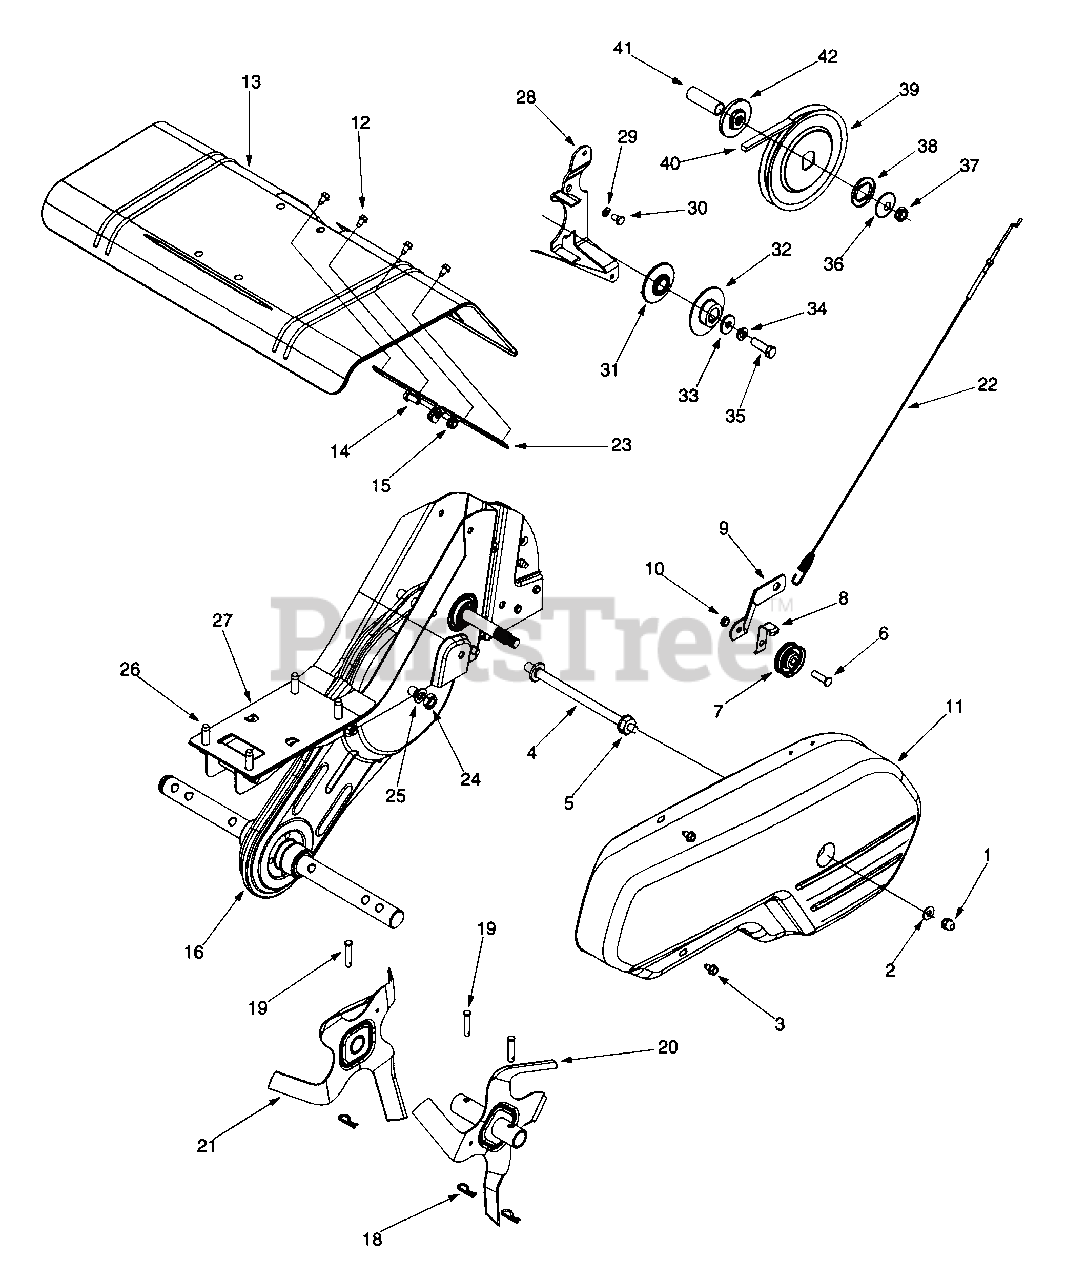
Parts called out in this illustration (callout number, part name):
1	Hex L-Stop nut 1/4-28
2	Flat Wash. .266" I.D. x .625" O.D.
3	Hex Washer Screw 1/4-20 x .5"
4	Belt Cover Bolt
5	Hex Flange Top L-Nut 5/16-18
6	Hex Hd. Scr. 3/8-16 x 1.25" Lg.
7	Fl-Idler 2.12" O.D.
8	Idler Belt Keeper
10	Hex Cent. Jam Nut 3/8-16 Thd.
12	Hex Washer Screw 1/4-20 x .5"
15	Hex Flange Top L-Nut 5/16-18
16	Chain Case Assembly Complete
18	Internal Cotter Pin
19	Clevis Pin
22	Forward Clutch Cable
24	L-Wash. 7/16" I.D.
25	Hex Nut 7/16-20 Thd.
26	Hex Washer Screw 3/8-16 x 1.25"
29	Lock Washer 5/16
30	Hex Bolt 5/16-24 x .5"
31	Inner Engine Pulley Half
32	Outer Engine Pulley Half
33	Flat Washer .385 ID x 1.0 OD
34	Lock Washer 3/8
35	Hex Bolt 3/8-24 x 1.25"
36	Bell-Wash. .525" I.D. x 1.5" O.D.
37	Hex Jam Nut 1/2-20 Thd. (Gr. 5)
38	Retainer Washer Bearing
39	Fl-Pulley 6" Dia.
40	V-Belt (Forward)
41	Spacer .64" Dia. x 2.4" Lg.
42	Pulley Mounting Adapter
